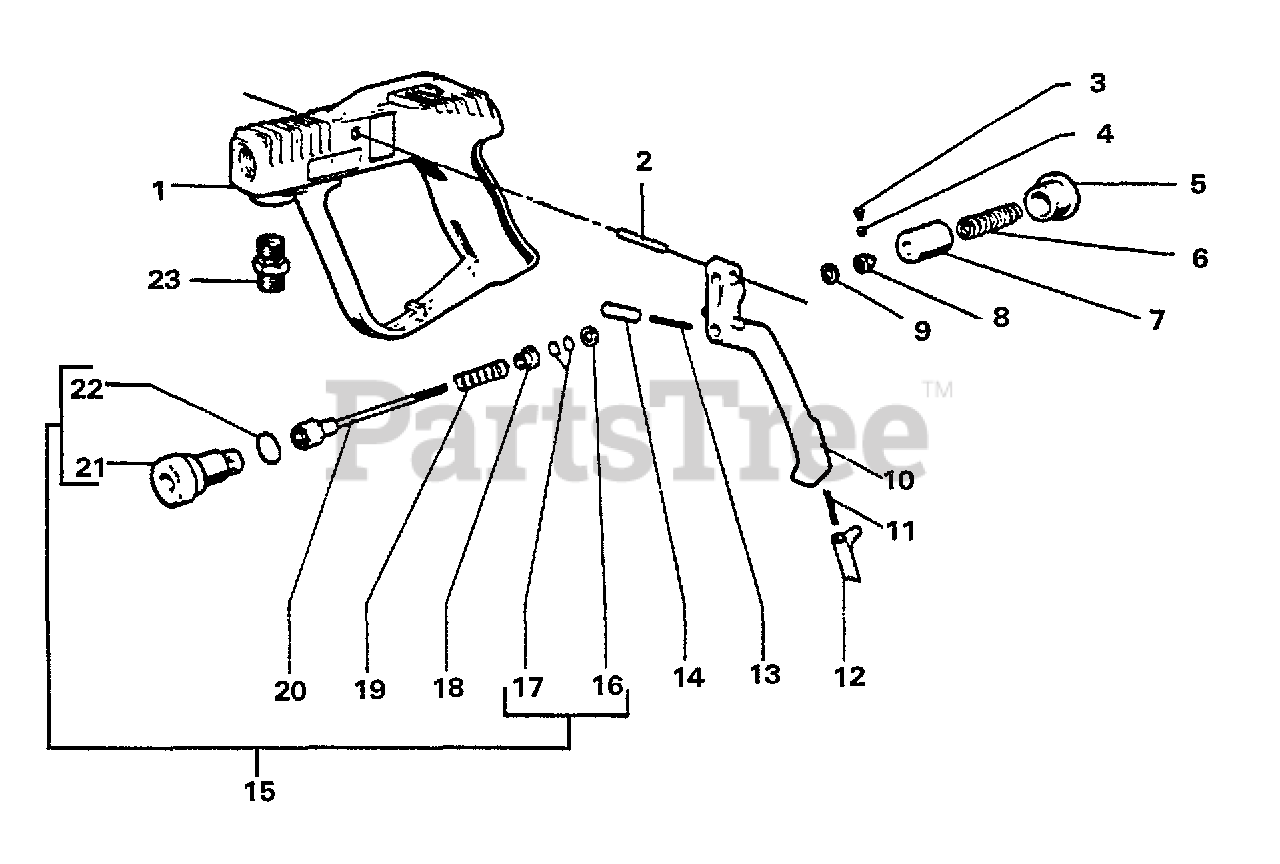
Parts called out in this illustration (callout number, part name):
1	GRIP, BODY
2	PIN, CYLINDER
3	SPRING
4	BALL
5	CAP
6	SPRING
7	GUIDE, SPRING
8	RINGNUT
9	NUT - 4
10	LEVER, COMMAND
11	SPRING
12	PIN, LOCK SAFETY CATCH
13	SPRING
14	SHAFT
15	KIT, GRIP CONTROL VALVE
16	RING, BACK-UP
17	O-RING
18	GUIDE, SPRING
19	SPRING
20	SHUTTER ROD ASSY
21	SEAT, VALVE
23	COUPLER
